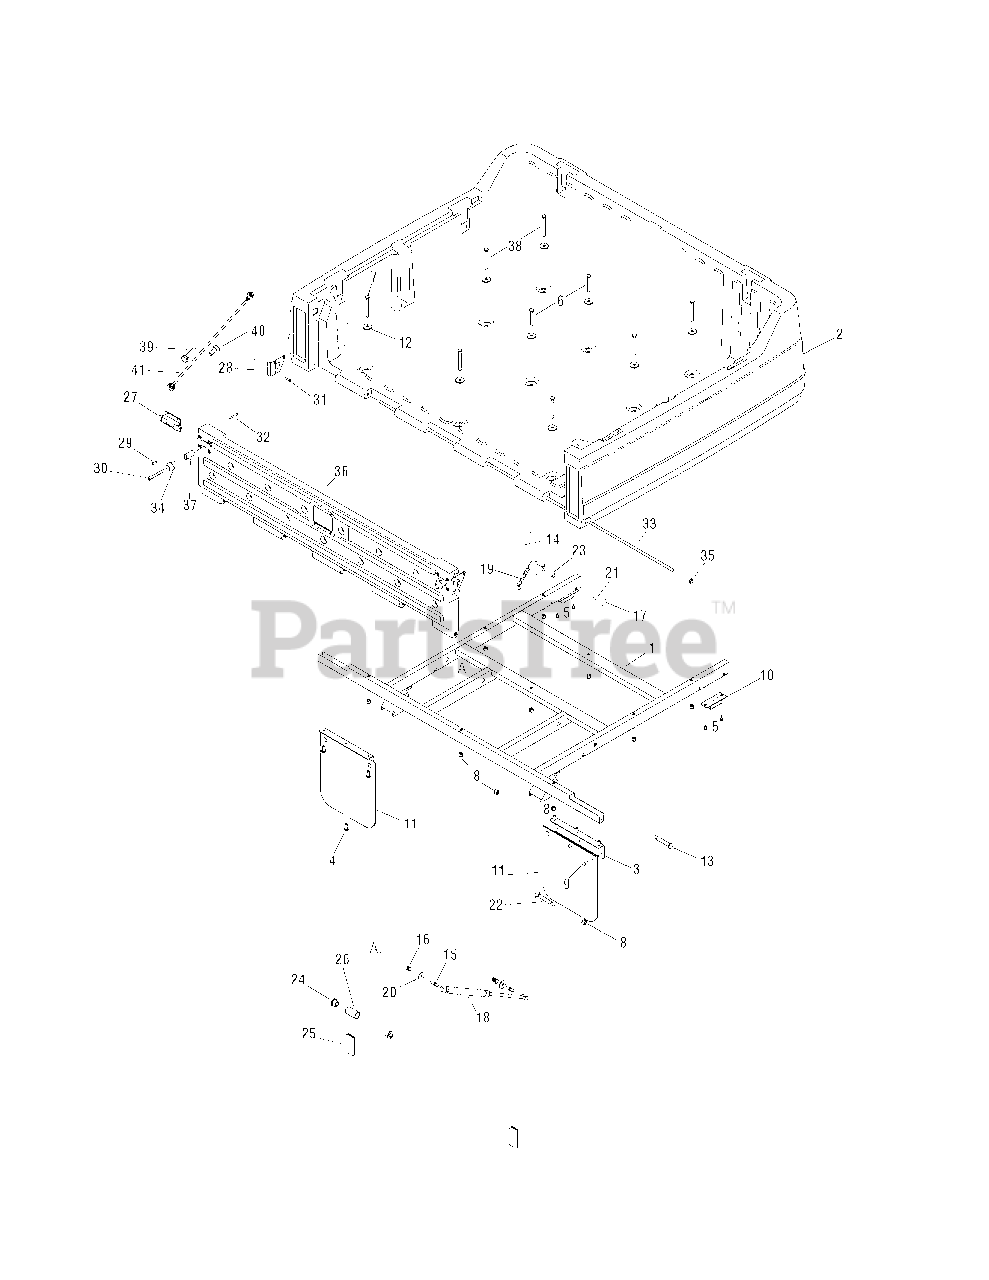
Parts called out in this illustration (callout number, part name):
3	Mud Flap Bracket
4	Hex Screw, 3/8-16 x.75
5	Self Tap Screw, 1/4-20 x.500
6	Hex Screw, 3/8-16 x 2.50
7	Hex Screw, 3/8-16 x 3.25
8	Hex Lock Nut, 3/8-16
9	Pop Rivet
10	Bumper, Suspension
12	Flat Washer,.406 x 1.26 x.17
13	Shoulder Screw, 1/2 x 2.50 Lg.
14	Latch Assembly
15	Ball Stud, 5/16-18
16	Insert Nut. 5/16-18
17	Cotter Pin
18	Gas Spring, 6.91 Stroke
19	Extension Spring
20	Flat Washer,.344 x 1.125 x.12
21	Flat Washer,.406 x .875 x .059
22	Shoulder Bolt, 1/2 x 2.50
23	Spacer,.385 x.625 x.700
24	Flange Bearing, .51
25	Tubing Plug
26	Leaf Spring Rear Spacer
27	Tailgate Latch Assembly
28	Kick Plate - LH
29	Screw, 10-24 x 5/8
30	Hex Screw, 5/16-18 x 2.75
31	Screw, 1/4-14 x .625
32	Machine Screw, #10-24 x 1.625
33	Tailgate Hinge
34	Knob
37	Spacer,.315ID x.375OD x 2.25
38	Hex Screw 3/8-16 x 3.50
39	Hex Screw 1/4-20 x 1.00
40	Cap Screw 1/4-20 x .750
41	Polybed Utility Cable
